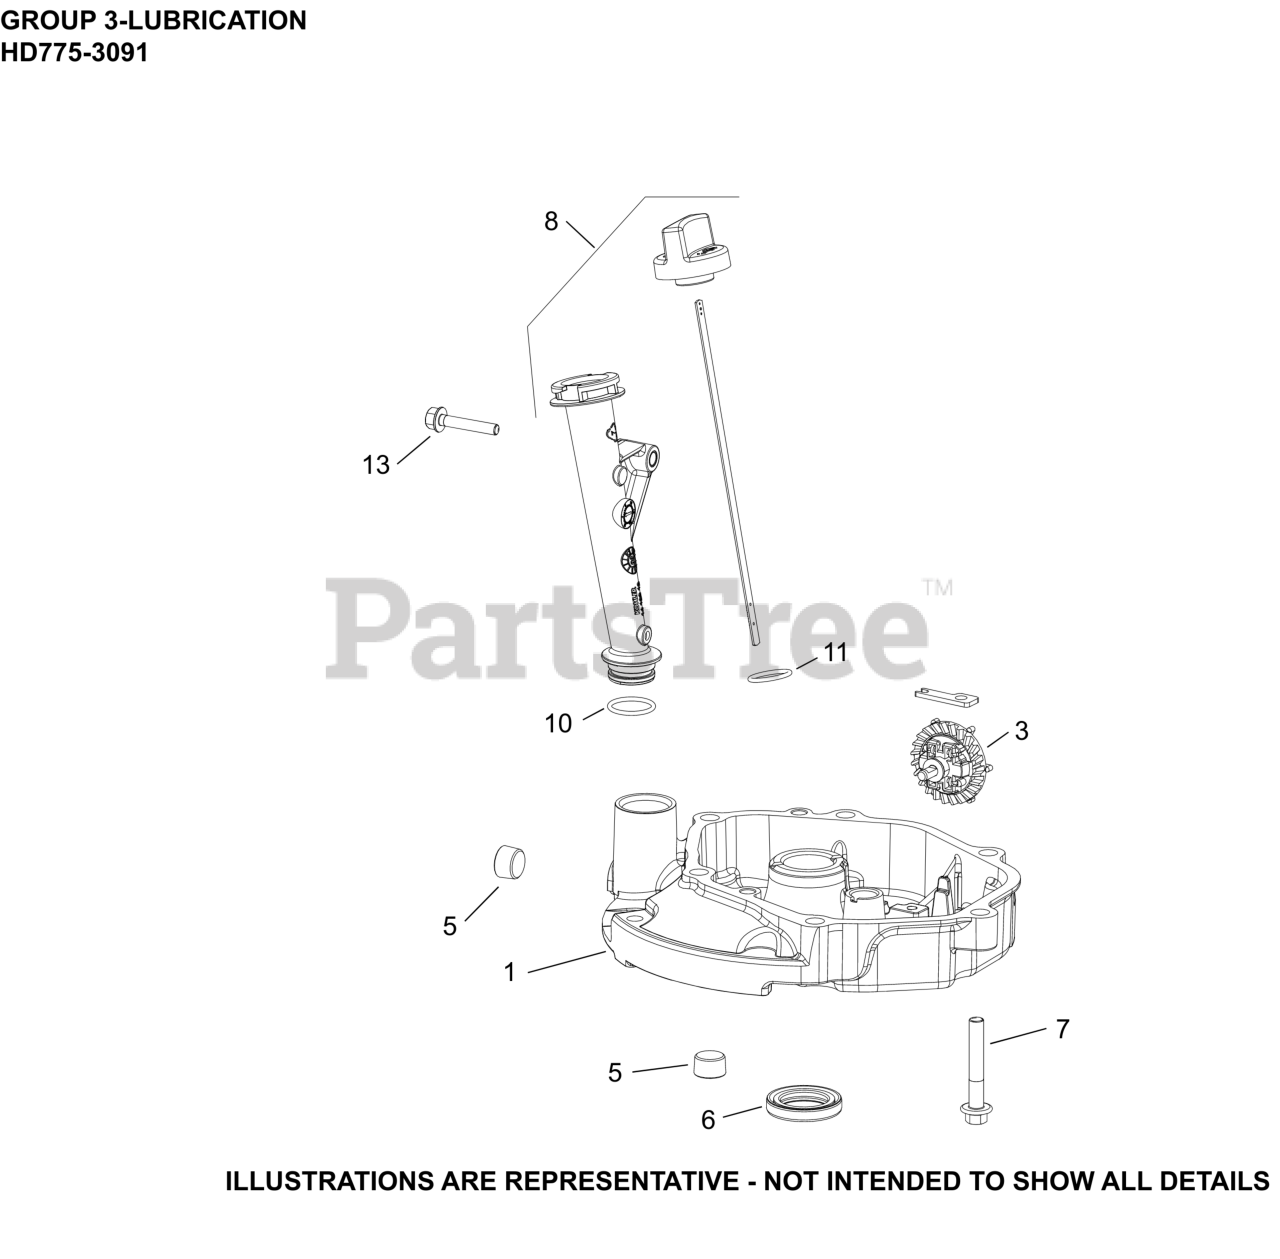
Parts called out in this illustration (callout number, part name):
1	KIT, OIL PAN
3	GEAR ASSEMBLY, GOVERNOR
5	PLUG, PIPE (W/SEALANT)
7	SCREW, HEX FLANGE (M8)-USE 25 086 456-S
8	TUBE ASSEMBLY OIL FILL-USE 14 123 20-S
10	O-RING, OIL FILL TUBE
11	O-RING (CAP)
13	SCREW, HEX FLANGE (M6)-(#25086435S)
